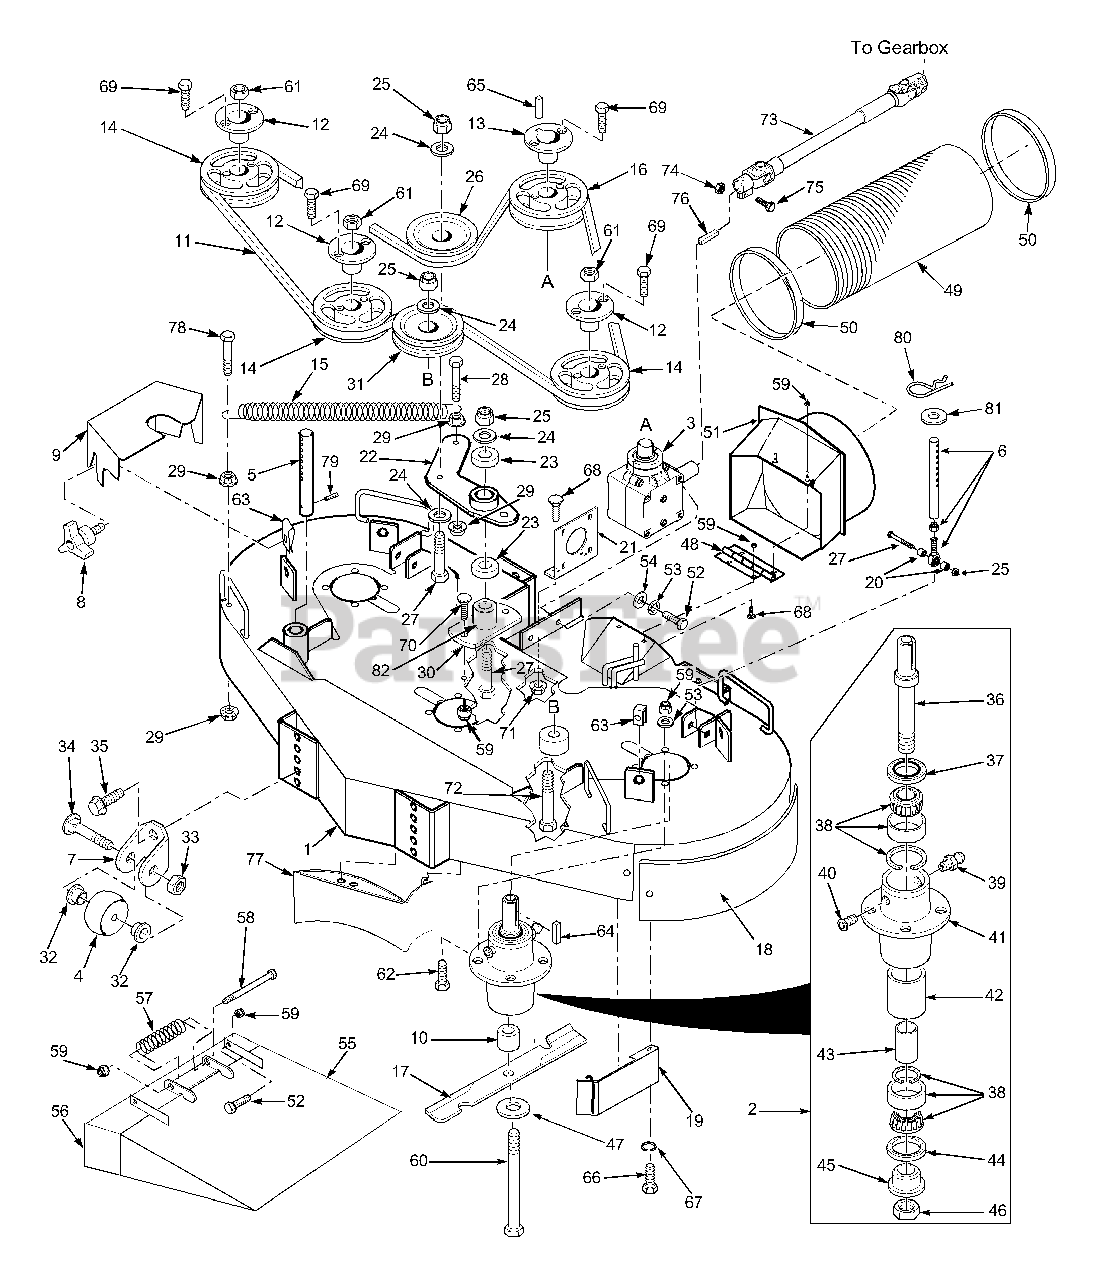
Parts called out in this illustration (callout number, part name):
1	Cutter Deck with Decals
2	Spindle Assembly
3	Gearbox, Cutter Deck
4	Wheel, Anti-Scalp
5	Pin, Front Deck Height Adjust.
6	Pin, Rear Deck Height Adjust.
7	Bracket, Anti-Scalp Wheel
8	Knob w/Stud
9	LH Belt Cover
10	Spacer, Spindle Bottom
11	Belt, Cutter Deck Drive
12	Hub, Tapered 1.125" bore
13	Hub, Tapered 1.00" bore
14	Pulley, 5.75" OD Tapered Bore
15	Spring, Belt Tension
16	Pulley, 6.35" OD Tapered Bore
17	Blade, Cutter 16.5" LH
18	Skirt, Weldment Bolt On
19	Baffle, Bolt On
20	Spacer
21	Plate, Gearbox Mounting
22	Idler Arm
23	Bearing, Ball
24	Flat Washer 3/8"
25	Nut, Elastic Stop 3/8-16
26	Pulley, Idler
27	Bolt, Hex Head 3/8-16 x 3"
28	Bolt, Hex Head 3/8-16 x 1.5 GR8
29	Nut, Serr. Flng. 3/8-16
30	Pivot, Idler Arm
31	Pulley, Idler 5.0"
32	Bushing .376 ID Oilite
33	Lock Nut, 3/8-16 Center Lock
34	Bolt, Carriage 3/8-16 x 4.0"
35	Bolt, Hex Serr. Flng. 3/8-16 x 1.0"
36	Shaft, Spindle
37	Seal, Top
38	Bearing Assembly
39	Grease Fitting
40	Relief Fitting, Grease
41	Housing, Spindle
42	Spacer, Outside
43	Spacer, Inside
44	Seal, Bottom
45	Bushing, Spindle Bottom
46	Nut, Special 1 - 1/16-18
47	Flat Washer 5/8"
48	Hinge, Rear Chute
49	Tube, Discharge 8" ID
50	Clamp, Duct 8"
51	Chute, Rear Discharge
52	Bolt, HH 5/16-18 x 1.0"
53	Lockwasher, 5/16"
54	Washer, Flat 5/16"
55	Chute, Side Discharge
56	Bracket, Side Discharge Chute
57	Spring, Discharge Chute
58	Bolt, HH 5/16-18 x 4.5"
59	Nut, Elastic Stop 5/16-18
60	Bolt, 5/8-11 x 9.5" LH Thread
61	Nut, 5/8-11 LH Thread
62	Bolt, HH 5/16-18 x 1.25"
63	U-Nut, 3/8-16
64	Key, 1/4 x 1/4 x 2.0"
65	Key, 1/4 x 1/4 x 1.25"
66	Bolt, 3/8-16 x 1.0"
67	Lock Washer 3/8" Spring
68	Bolt, Carriage 5/16-18 x .75"
69	Bolt, HH 1/4-20 x .75"
70	Bolt, Carriage 5/16-18 x 1.0"
71	Nut, Serr. Flng. 5/16-18
72	Bolt, HH 3/8-16 x 3.5"
73	Driveshaft
74	Nut, Elastic Stop 3/8-16
75	Bolt, Hex Head 3/8-16 x 1-3/4"
76	Key, 1/4 x 1/4 x 1-1/4"
77	Baffle, Rear
78	Bolt, Hex Head 3/8-16 x 1-3/4"Gr.8
79	Roll Pin
80	Hair Pin Cotter
81	Flatwasher, 5/8-.688 x 1.750 x .134
82	Pivot, Idler Short
